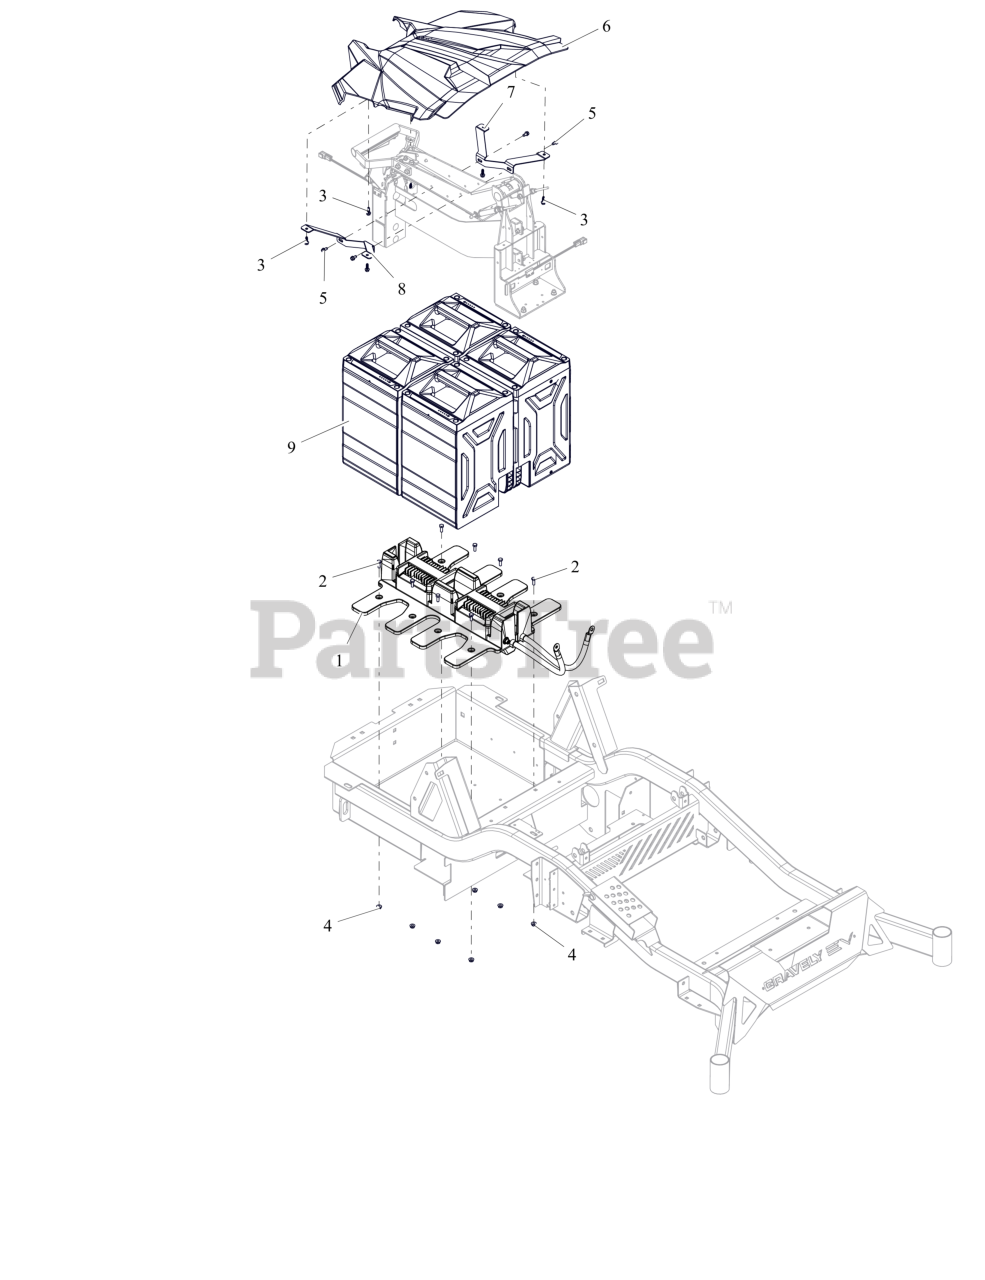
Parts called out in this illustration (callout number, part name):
1	BASE, BATTERY BUSSBAR
2	BLT, HEX .25-20X.75 G5 ZCC
3	SCR, PLASTITE-HWH 0.25 X 0.75 ZC120
4	NUT-LK-CTR-FLG .25-20 ZC120
5	SCR-TAP .25-20X.50 HWH ZCC
6	HOOD, PRO - TURN EV
7	SUPPORT, HOOD EVZT (BLACK)
8	SUPPORT, HOOD EVZT (BLACK)
9	KIT, EV BATTERY
